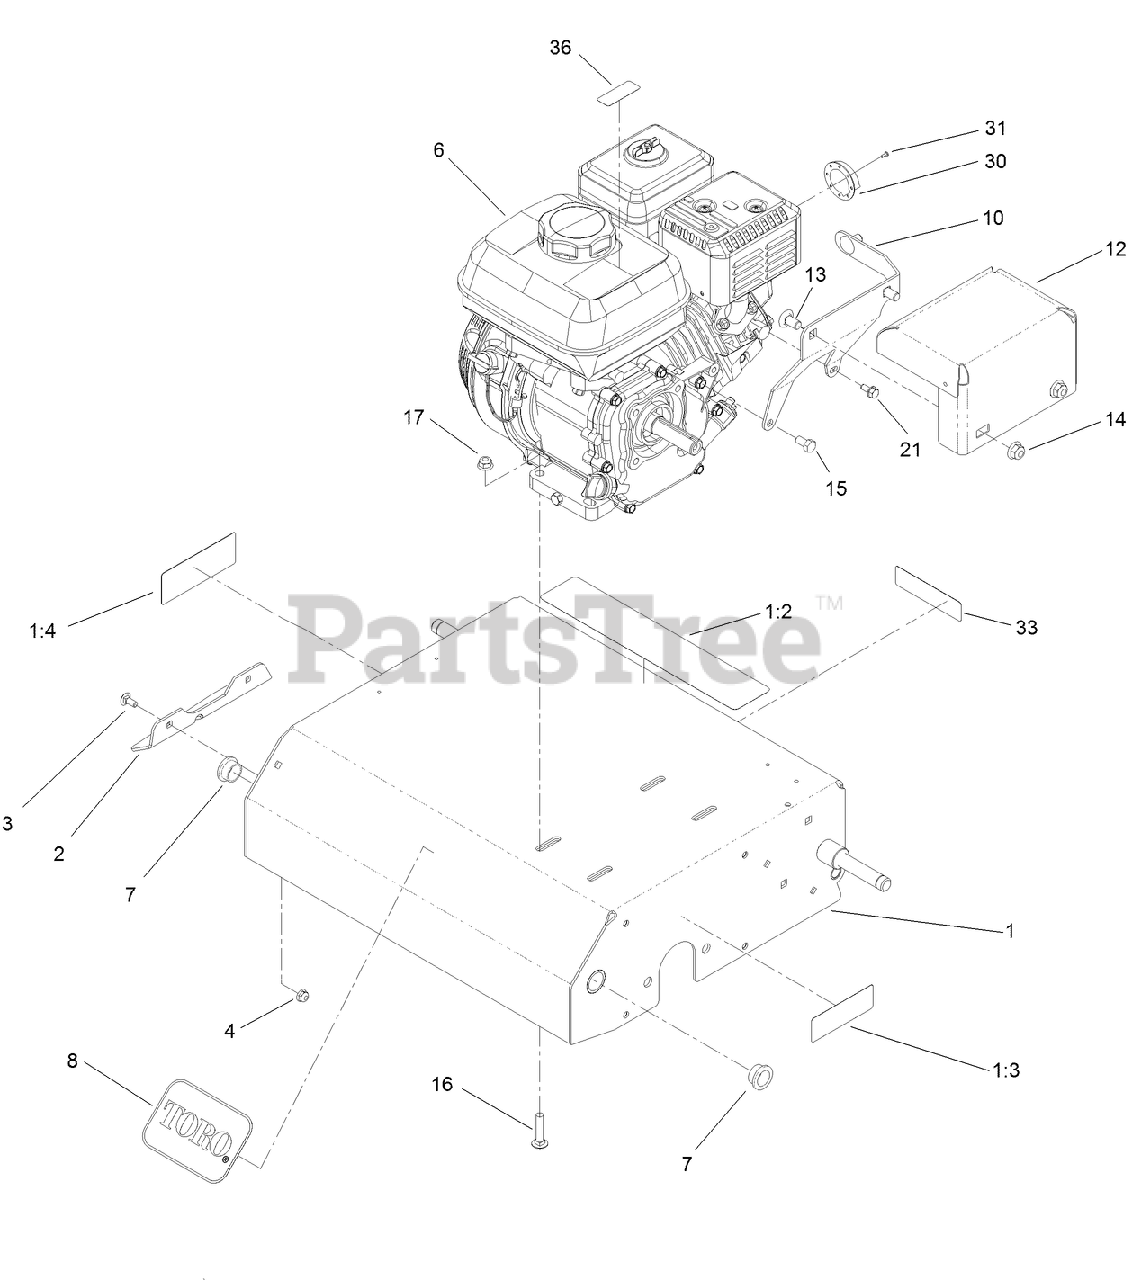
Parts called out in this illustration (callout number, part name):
1	FRAME ASM
1:2	DECAL-WARNING
1:3	DECAL-WARNING
1:4	DECAL-DANGER
2	GUARD-HAND
3	SCREW-CARR
4	NUT-HF
6	ENGINE-HONDA, GX160
7	BUSHING
8	DECAL
10	MOUNT-SHIELD, HEAT
12	SHIELD-HEAT
13	SCREW-CARR
14	NUT-HF, NI
15	SCREW-HH
16	BOLT-CARR
17	NUT-HF, NI
21	SCREW-HWH
30	DEFLECTOR
31	SCREW-PPHTF
33	DECAL-ARRESTER, SPARK
36	DECAL-WARNING, ETHANOL
